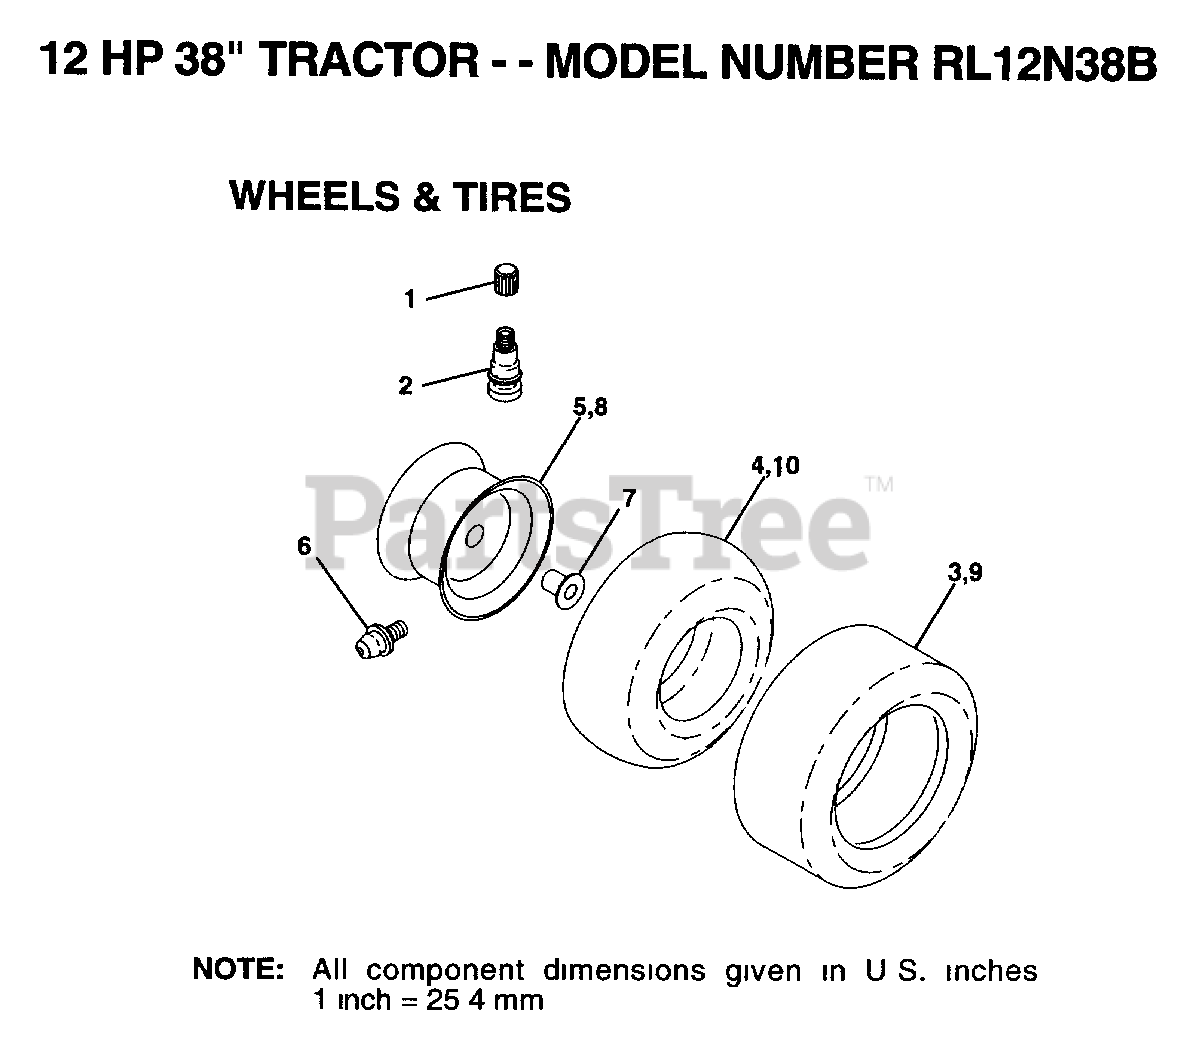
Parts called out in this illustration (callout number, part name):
1	VALVE CAP
2	VALVE STEM LT
4	TUBE.5.3/4.5/6
6	FITTING LT
7	"FLANGE, BEARING"
9	TIRE.TS2.18X8.5
10	TUBE.18X9.5-8
